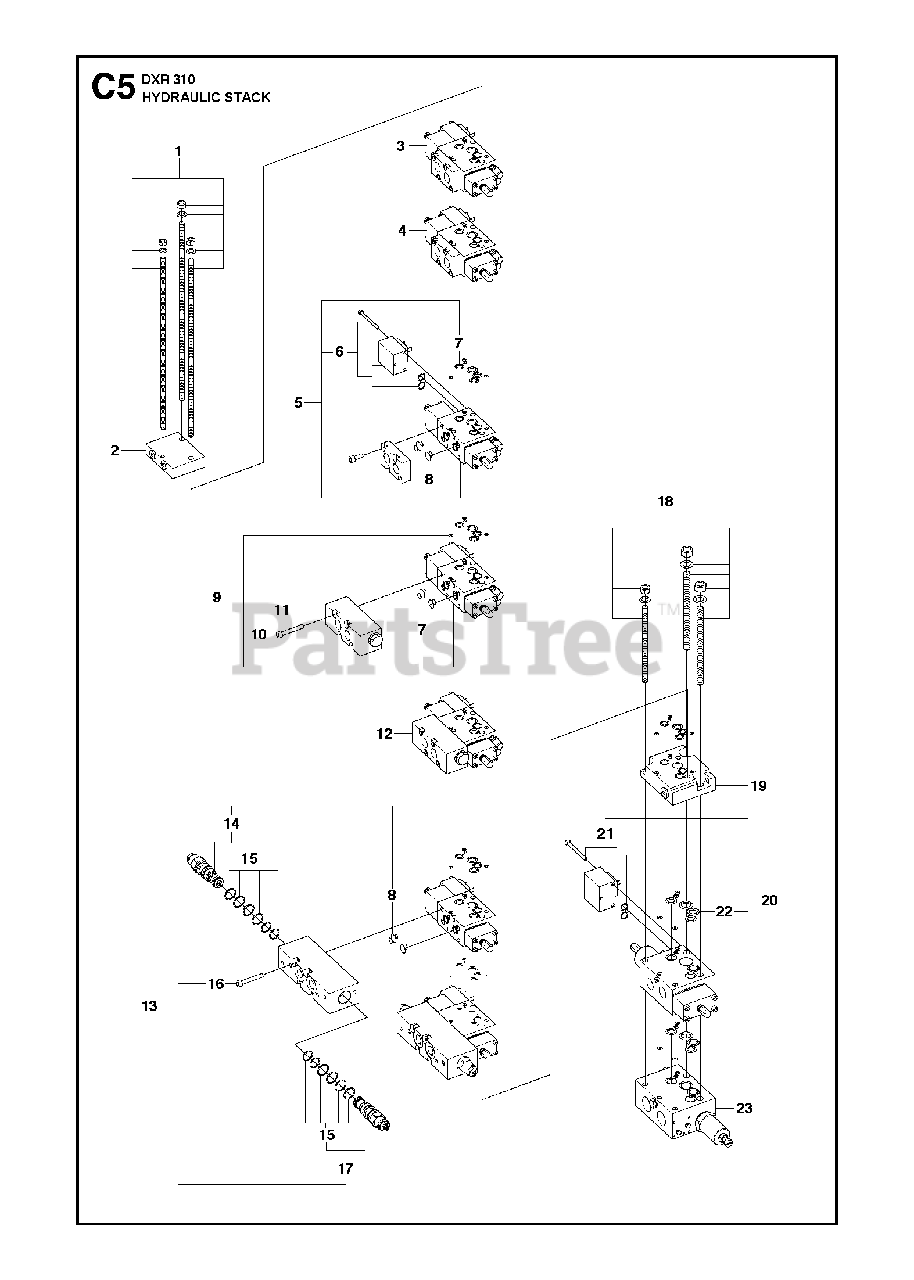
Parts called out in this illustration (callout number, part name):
1	TAPExtra hydraulic function 1 (6 sections)
1	TAPExtra hydraulic function 2 (7 sections)
16	SCREW IHSCM
